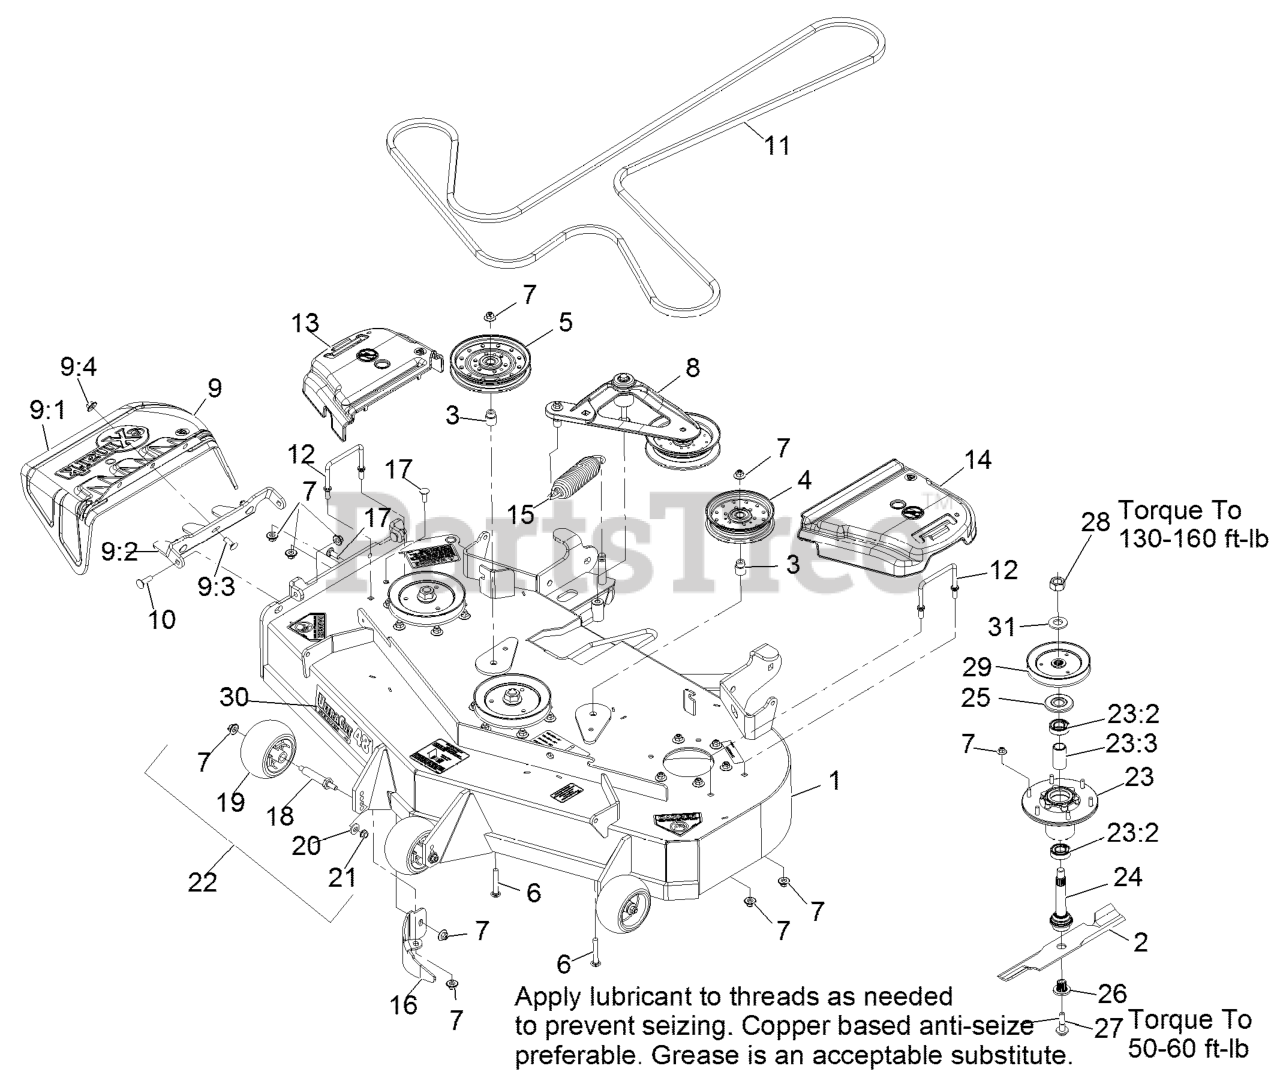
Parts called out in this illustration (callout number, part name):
1	ASM,DECK W/DECALS 48
3	BUSHING-IDLER
6	SCREW-CARR
7	Nut-Nyloc 3/8-16 Flg
8	DECK IDLER ASM
9	ASM,DISCHARGE CHUTE
9:1	CHUTE,DISCHARGE
9:2	BRACKET,DISCHARGE CHUTE
9:3	SCREW-CARR
9:4	Nut-Nyloc 3/8-16 Flg
10	Bolt-Carriage 3/8-16 X 1 1/4
11	BELT
12	WIREFORM-COVER
13	COVER-BELT, RH
14	COVER-BELT, LH
15	SPRING-EXTENSION
16	BAFFLE-DOGLEG,LZS LZX VT4
17	SCREW-CARR
19	ROLLER-SCALP, ANTI
20	WASHER-BELLEVILLE
21	NUT-HHF, WHIZ
23	ASM-CUTTER HSG WITH BEARINGS
23:2	BEARING-BALL
23:3	SPACER-BEARING
24	ASM-SPINDLE AND SEAL
25	GUARD,BEARING TOP .989
26	BUSHING,SPLINED
27	SCREW,SEMS 1/2-20 X 2.19
28	NUT-HEX
29	SHEAVE,BLADE DRIVE 5.90
30	DECAL,ULTRACUT 48 SERIES
